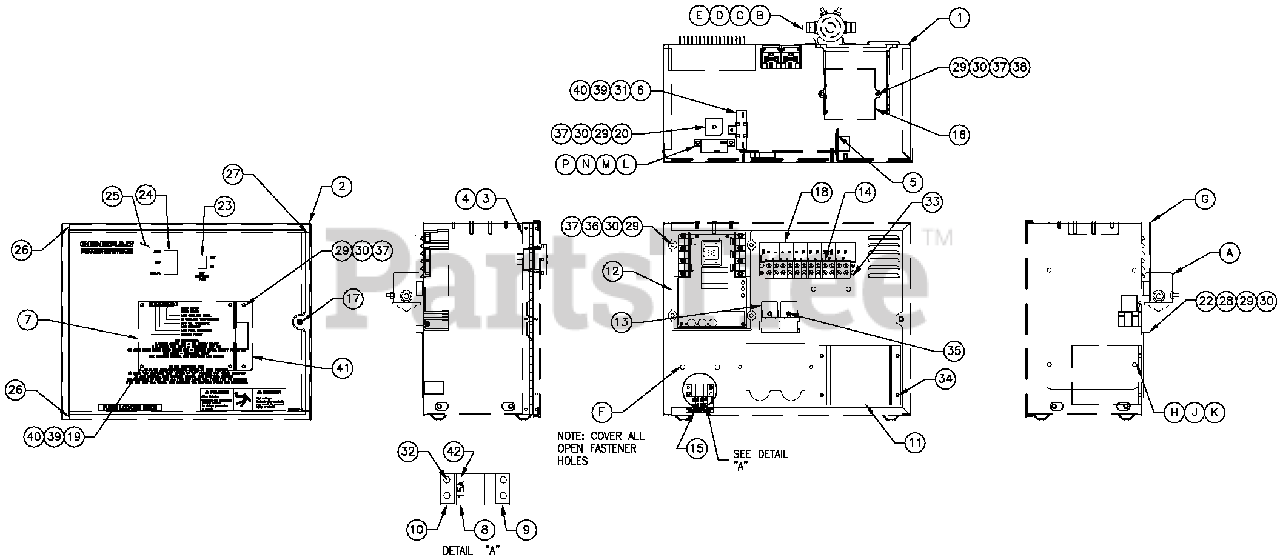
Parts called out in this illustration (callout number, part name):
1	ENCL HSB CONTROL PANEL
2	COVER, CONTROL PANEL
3	HINGE, CONTINUOUS H PANEL
4	RIVET POP .125 X .275 SS
5	SCREW PPPH HI-LO #4-24 X 3/8
6	WASHER FLAT M3
7	ASSY PCB R-200A CNTRL 1800
8	HOLDER, FUSE WICKMANN 178.6150
9	ADPTR, RH SIDE WICKMANN 178.6191
10	ADPTR, LH SIDE WICKMANN 178.6192
11	ASSY PCB 2AMP UL BATT CHGR12V
12	ASSYPCBoHI-PWRVOLTAGERGLTR
13	RELAY, 12VDC C FORM W/DIODE
14	BLOCK TERM 2 0A 12 X 6 X1100V
15	DECALCPLCNTPNLFUSES
16	ASSYPCBBOSCHGOVDRIVER
17	M5 0.8CAPTIVEPANELKNLDHD
18	DECALCPL3.9LTB1
19	SPACER9.5H3.2ID
20	DIOBRIDGE25A600V
22	PLATEHARNESSCLAMP
23	SWITCH ROC DPST125VSPD
24	SWITCHROCDPDTON-OFF-ON
25	DECALCONTROLFLEB
26	SEALCOVER3.18 12.7 382
27	SEALCOVER3.18 12.7 283
28	SCREW HHPMM5-0.8X 12
29	WASHER FLAT M5
30	WASHERLOCKM5
31	RES WW 15R 5% 25W QK CONN
32	SCREW PHTTM3.5-0.6X 10
33	SCREW PHTTM3.5-0.6X 16
34	SCREW PHTT M4-0.7 X 12 ZYC
35	SCREW PHTT M4-0.7 X 10 ZYC
36	SCREW PPHM M5-0.8 X 50 ZNC
37	NUTHE M5-0.8G8YELCHR
38	SCREW PPHM M5-0.8X30SS
39	WASHERLOCKM3o
40	NUT HEX M3-0.5 G8 YEL CHR
41	SUPPORTANGLEPCB
42	FUSE ATO TYPE 15 AMP (BLUE)
43	HARN R-200 CTRL PNL 1800 RPM
A	RELAY SOLENOID 12VDCPNLMNT
B	SCREW HHC 1/4-20 X 3/4 G5
C	WASHERoFLATo1/4-M6oZINCo
D	WASHERoLOCKoM6-1/4o
E	NUToHE o1/4-20oSTEELo
F	SEAL WEATHER .45"DIA
G	COVERoCONTROLoPANELoSIDEo
H	SCREW PPHM M5-0.8 X 12 ZNC
J	WASHERoLOCKoM5o
K	WASHER FLAT M5
L	CB 5.5A X 1P ETA 46-500-P
M	WASHERoFLAToM3o
N	WASHERoLOCKoM3ooo
P	NUT HEX M3-0.5 G8 YEL CHR
